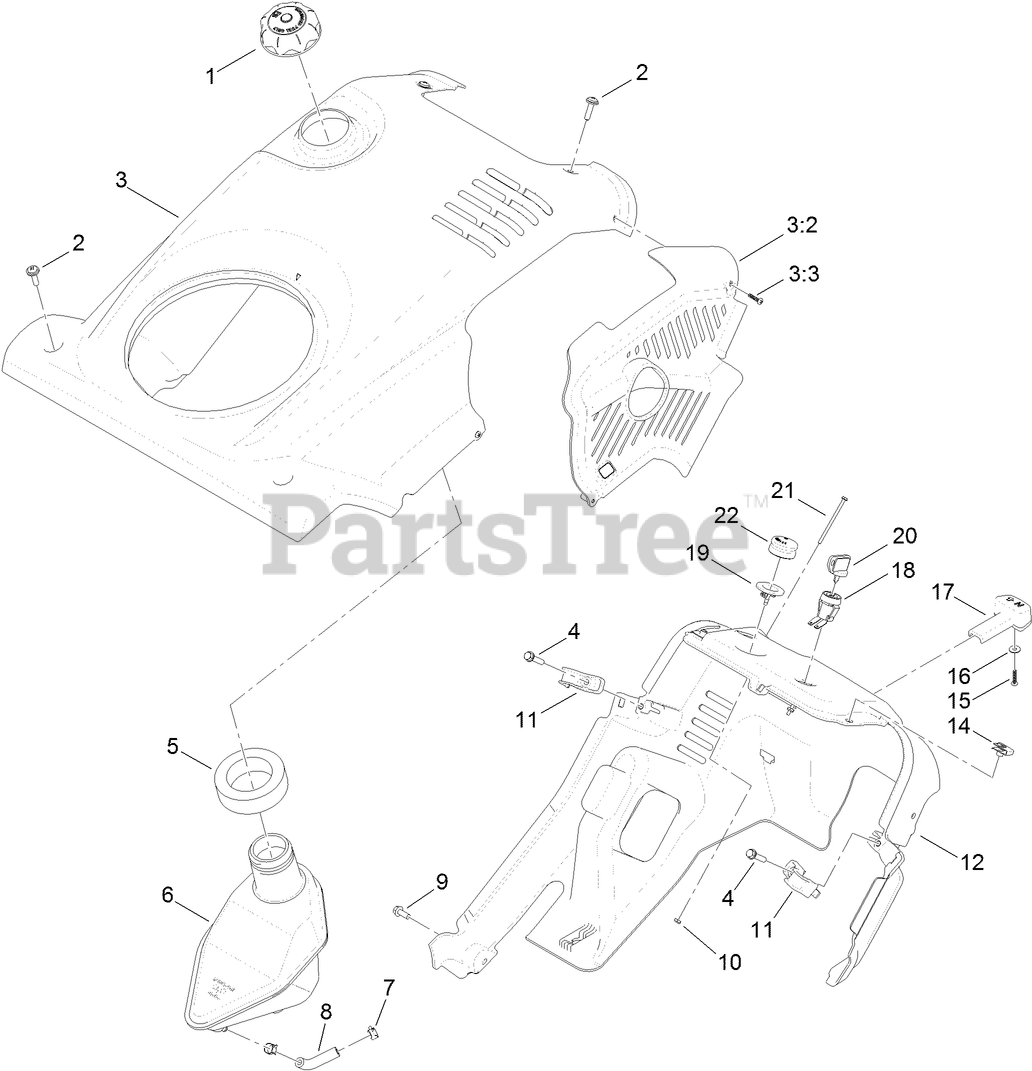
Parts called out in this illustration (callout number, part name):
2	SCREW-PPH
3	SHROUD ASM
3:2	BAFFLE-EXHAUST
3:3	SCREW-PPH
4	SCREW-PLASTITE
5	SEAL-TANK
6	TANK-FUEL, GAS
7	CLAMP-HOSE
8	HOSE-FUEL
9	SCREW-HWH
10	NUT-HEX
11	CLIP-SHROUD
12	SHROUD-LOWER
15	SCREW-PPH
16	WASHER-PLAIN
17	KNOB-CHOKE
18	SWITCH
19	BODY-PRIMER
20	KEY-IGNITION
21	SCREW-HWH
22	BULB-PRIMER
